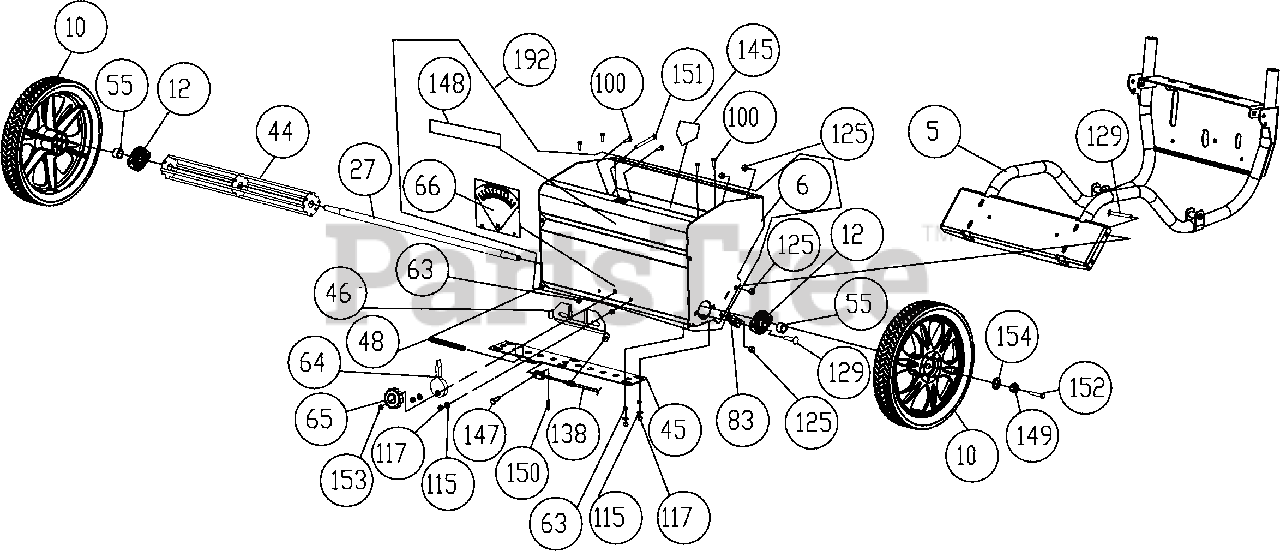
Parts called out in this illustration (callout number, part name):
5	FRAME SUPPORT OS900SP WA
6	SEED BOX WA
10	FRONT WHEEL 14" ASSY
12	BEARING & FLANGETTE ASSY
27	AXLE SEED BOX
44	WHEEL PADDLE SEED WA
45	PLATE SEED CONTROL OS900SP
46	BRACKET CONTROL SEED RATE
48	SPRING EXTENSION .5 X 5.00
55	SPACER SEED BOX AXLE OS900SP
63	SPACER SEED PLATE OS900SP
64	DIAL SEED INDICATOR
65	KNOB 5/16"-18 X 5/8" FLUTED
66	LABEL SEED FLOW RATE
83	CLAMP ROUTING FUEL LINE
100	SCREW 1/4" - 20 X .75 HWH
115	WASHER 1/4" SAE
117	LOCK NUT 1/4-20
125	NUT 5/16"-18 SER HEX WASHER FLNG ZP
129	BOLT CARRIAGE 5/16"-18 X 3/4" ZP
138	CABLE CLUTCH SEEDING CONTROL
145	LABEL WARNING OPEI
147	PIN CLEVIS 1/4" X .61
148	LABEL BADGING OS900SP
149	WASHER LOCK 5/16" TWISTED TOOTH HEAVY
150	PIN CLIP HITCH 0.051 X 3/4"
151	BOLT CARRIAGE 5/16"-18 X 1 1/4" ZP
152	SCREWCAP 5/16"-18 X 3/4" HCS ZP
153	NUT LOCK 5/16"-18 LT WT TH ZP
154	WASHER FENDER 5/16"
192	SEED BOX WAS OS900SP W/LABELS
